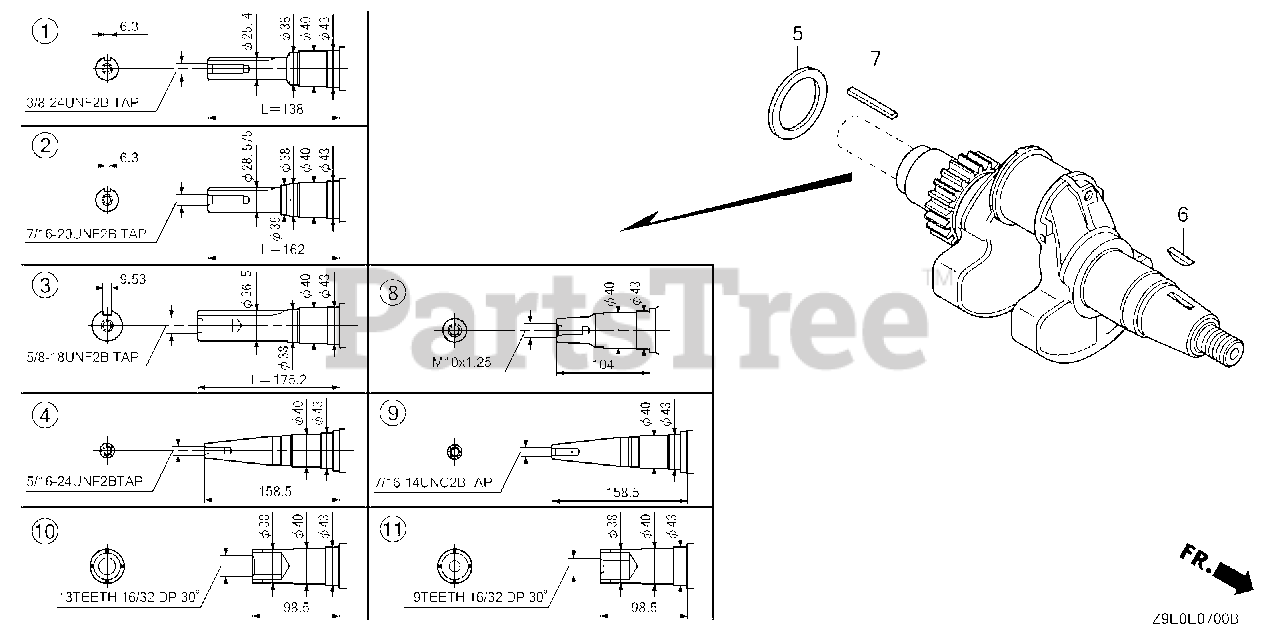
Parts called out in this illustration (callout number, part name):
4	CRANKSHAFT
5	WASHER, CRANKSHAFT THRUST
6	KEY, SPECIAL WOODRUFF (25X18)
